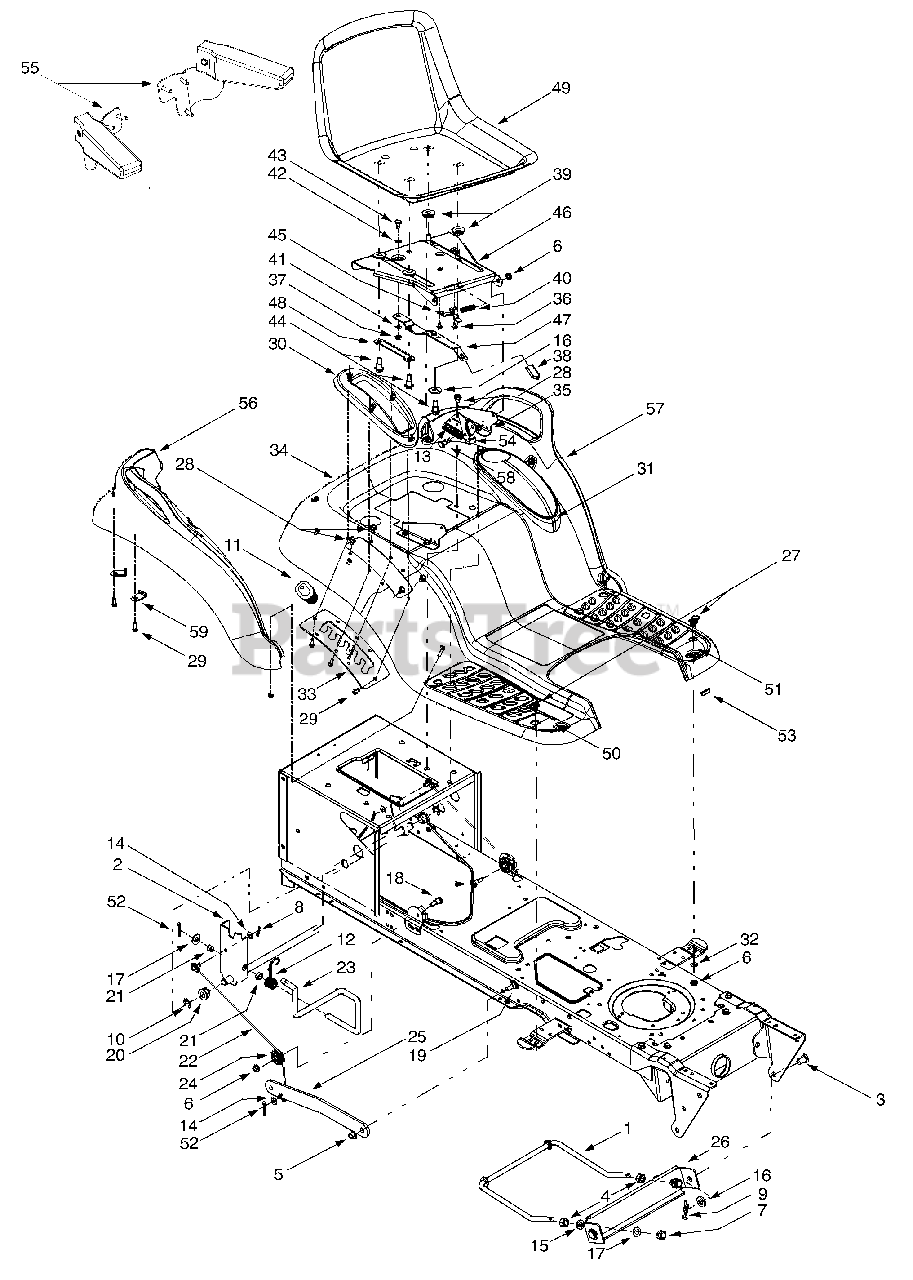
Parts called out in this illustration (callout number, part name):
1	Deck Stabilizer Rod (Model GT-2150)
2	Lift Shaft Assembly (Model GT-2150))
3	Clevis Pin, .5 x .78
4	Hex Nut, 1/2-13
5	Flange Lock Nut, 3/8-16
6	Flange Lock Nut, 5/16-18
7	Hex Nut, 1/2-13
8	Internal Cotter Pin
9	Internal Cotter Pin
12	Torsion Spring
13	Extension Spring, .84 x 4.6
14	Flat Washer, 5/16
15	Lock Washer, 1/2
16	Flat Washer, .31 x 1.062 x .134
17	Flat Washer, .51 x 1.12 x .06
18	Hex Cap Screw, 5/16-18 x .62
19	Shoulder Screw, 3/8-16
20	Hex Flange Bearing
21	Snap Flange Bearing
22	Lift Cable, 16.16
24	Roller Pulley
27	Carriage Bolt, 5/16 x .62
28	Self-tapping Screw, 5/16-18 x .625
29	Self-tapping Screw, 1/4-15 x .75
30	Lift Lever Cover
31	Cover w/ Cup Holder
32	Flat Washer, .349 x 1.0 x .063
36	Screw, #10-16 x .375
37	Hex Flange Lock Nut, 1/4-20
38	Seat Adjuster Grip
40	Compression Spring, .41 x 1.5
41	Spring Washer, .265 x .562 x .025
42	Flat Washer, .344 x .62 x .03
43	Shoulder Screw, .340 x .285,1/4-20
44	Shoulder Screw, .50 x .50, 3/8-16
48	Seat Adjustment Selector
49	High Back Seat w/ Drain Holes, Black
54	LH Seat Lift Bracket
55	Armrest Assembly
56	RH Fender Flare
57	LH Fender Flare
58	Shoulder Screw, .437 x .286
59	Fender Clips
